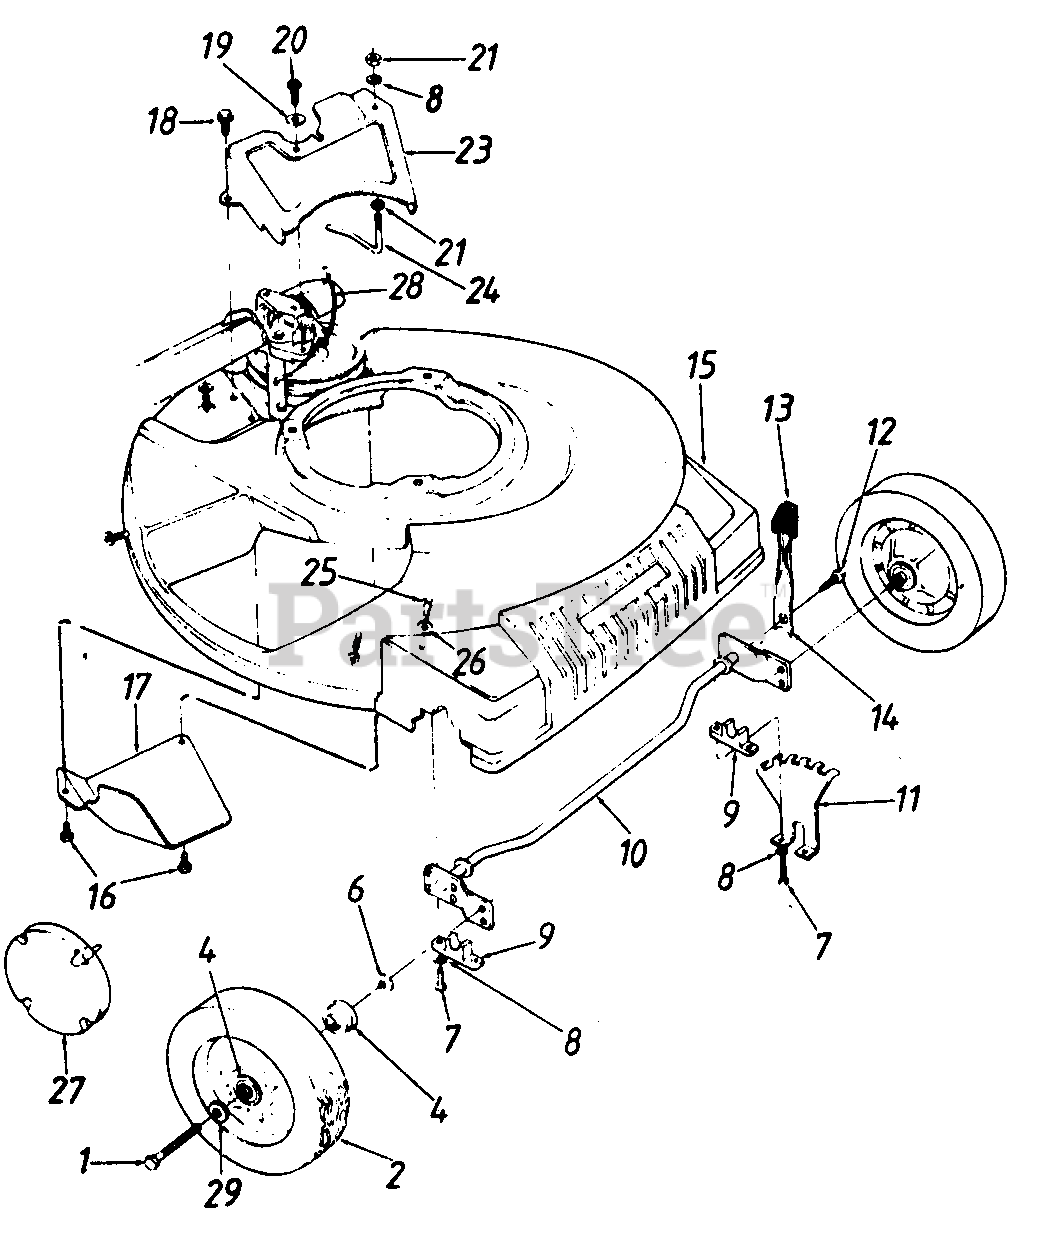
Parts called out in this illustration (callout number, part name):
1	Front Axle Bolt
2	Wheel Ass'y. Comp. 8 x 2"
4	Flange Ball Brg. .501" I.D.
6	Bell-Wash. .400" I.D. x .88
7	Hex Wash. Hd. B-Tap Scr. 1/4-20
8	L-Wash. '/4" I.D.
9	Block Bushing
10	Axle Ass'y.
11	Height Adj. Bracket
12	Hex Wash. Hd. B-Tap Scr. 1/4-20 x .75" Lg.
13	Knob
14	Spring Lever
15	Plastic Front End
16	Hex B-Tap Scr. 1/4-.38"
19	Bell-Wash. .265" I.D. x .75"
20	Hex Wash. Hd. B-Tap Scr. 1/4 x.62"
21	Hex Nut 1/4-20 Thd.
23	Transmission Belt Guard
24	S.P. Belt Guard
25	Truss B-Tap Scr. 5/16 x .751'
26	Bell-Wash. 5/16" I.D. x 5/8
27	Hub Cap
28	S.P. Cable 50" Lg.
29	Fl-Wash. .531 " I.D.
